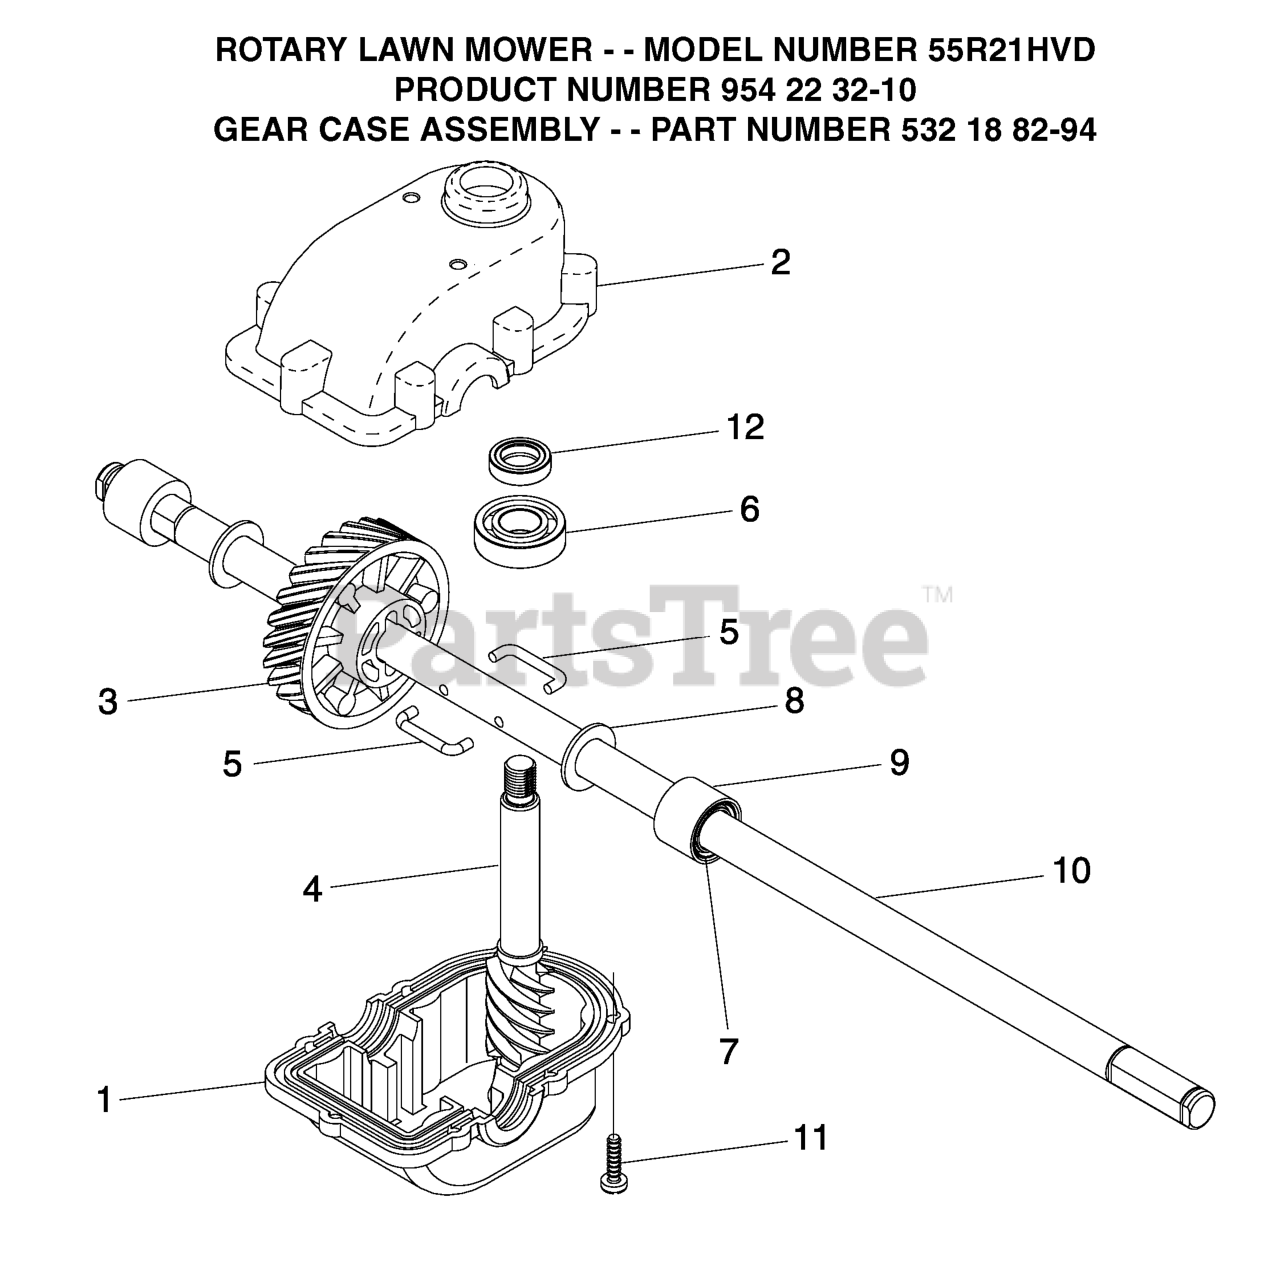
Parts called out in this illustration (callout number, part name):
1	CASE, LOWER
2	GEARCASE.HOUSING
3	GEAR.24.TOOTH.WALK.MOWER
5	WIRE, FORMED (15966)
7	SEAL.OUTPUT.SHAFT
10	SHAFT OUTPUT
12	SEAL INPUT SHAFT
